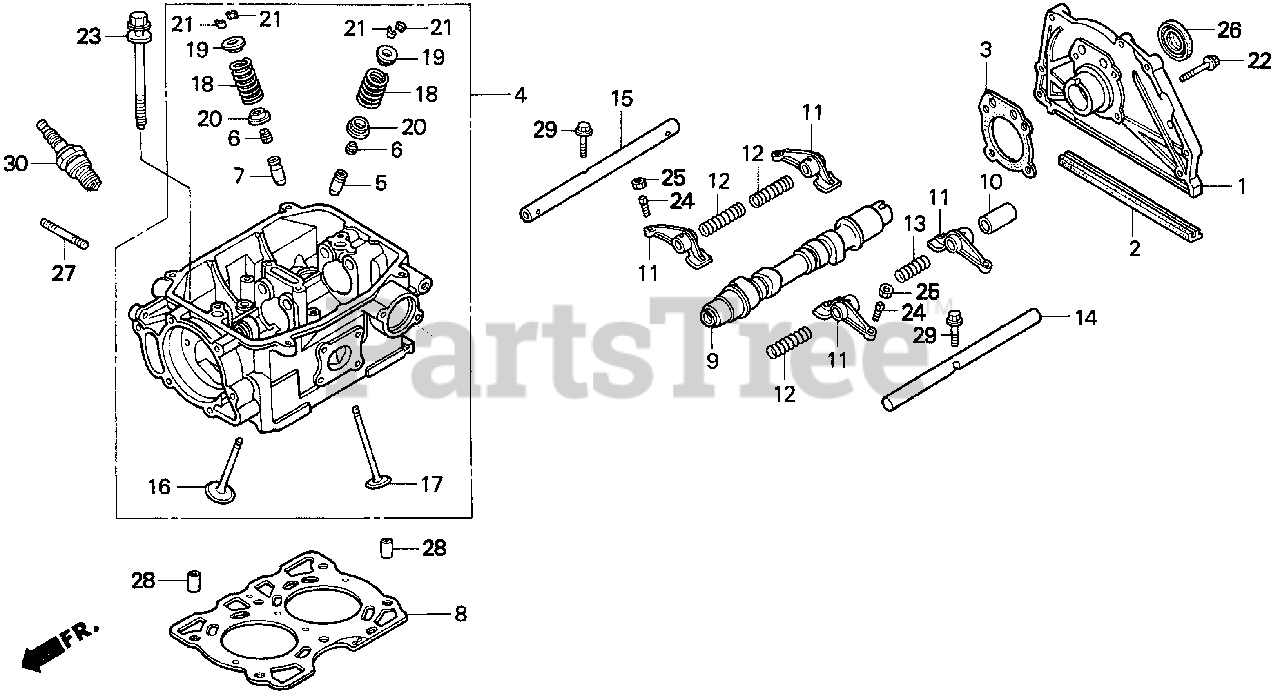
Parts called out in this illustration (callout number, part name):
1	COVER, RR. TIMING BELT
2	GASKET, RR. TIMING BELT COVER
3	GASKET, RR. TIMING BELT COVER
4	CYLINDER HEAD ASSY.
5	GUIDE, VALVE (OS)
6	SEAL, VALVE STEM (ARAI)
7	GUIDE, EX. VALVE
8	GASKET, CYLINDER HEAD
10	COLLAR, ROCKER ARM
11	ARM, ROCKER
12	SPRING, ROCKER ARM A
13	SPRING, ROCKER ARM B
14	SHAFT, IN. ROCKER
15	SHAFT, EX. ROCKER
16	VALVE, IN.
17	VALVE, EX.
18	SPRING, VALVE
19	RETAINER, VALVE SPRING
20	SEAT, VALVE SPRING
21	COTTER, VALVE
22	BOLT, FLANGE (6X30)
23	BOLT-WASHER (10X115)
24	SCREW, TAPPET ADJ.
25	NUT, TAPPET ADJ.
26	OIL SEAL (28X40X8)
27	BOLT 2, STUD (8X22)
28	PIN A, DOWEL (12X20)
29	BOLT, FLANGE (6X30)
30	SPARK PLUG (BPR5ES-11) (NGK)
30	SPARK PLUG (W16EPR-U11) (DENSO)
